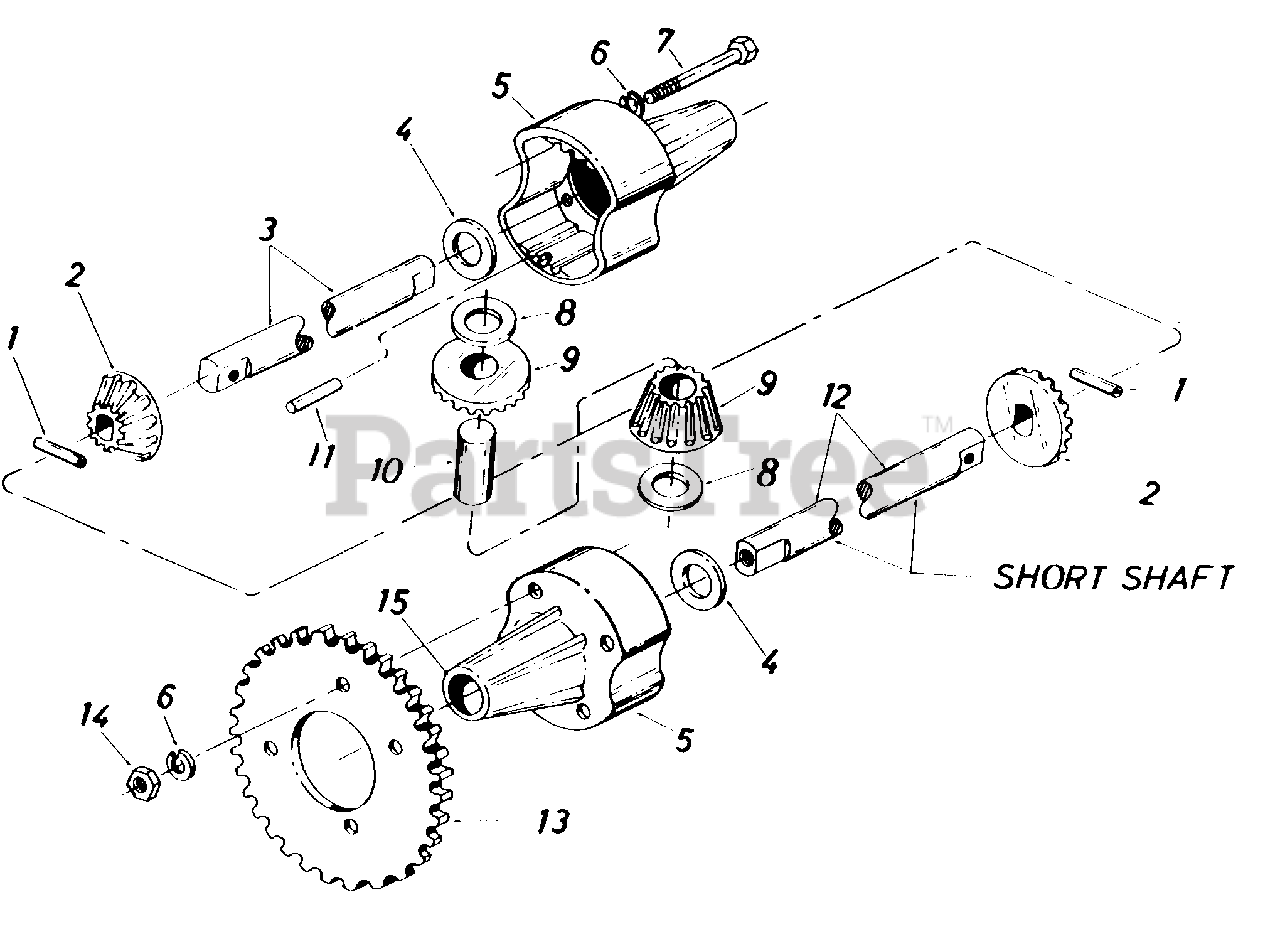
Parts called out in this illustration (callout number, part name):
1	Spring Pin Spiral 3/16" Dia. x 1.00" Lg.
2	Gear-Double"D" Hole
3	Shaft (Long) -15.11" Lg.
4	Fl-Wash. .760 I.D. x 1.49 O.D.
5	Housing Half
6	L-Wash. 5/16" I.D.
7	Hex Bolt 5/16-24 x 4.00" Lg.
8	Fl-Wash. .640 I.D. x .24 O.D.
9	Gear-Round Hole
10	Drive Pin
11	Dowel Pin 3/16" Dia. x .62" Lg.
12	Shaft (Short) 7.58" Lg.
13	Sprocket-48 Teeth
14	Hex Cent. L-Nut 5/16-24 Thd.
15	Flange Bearing
